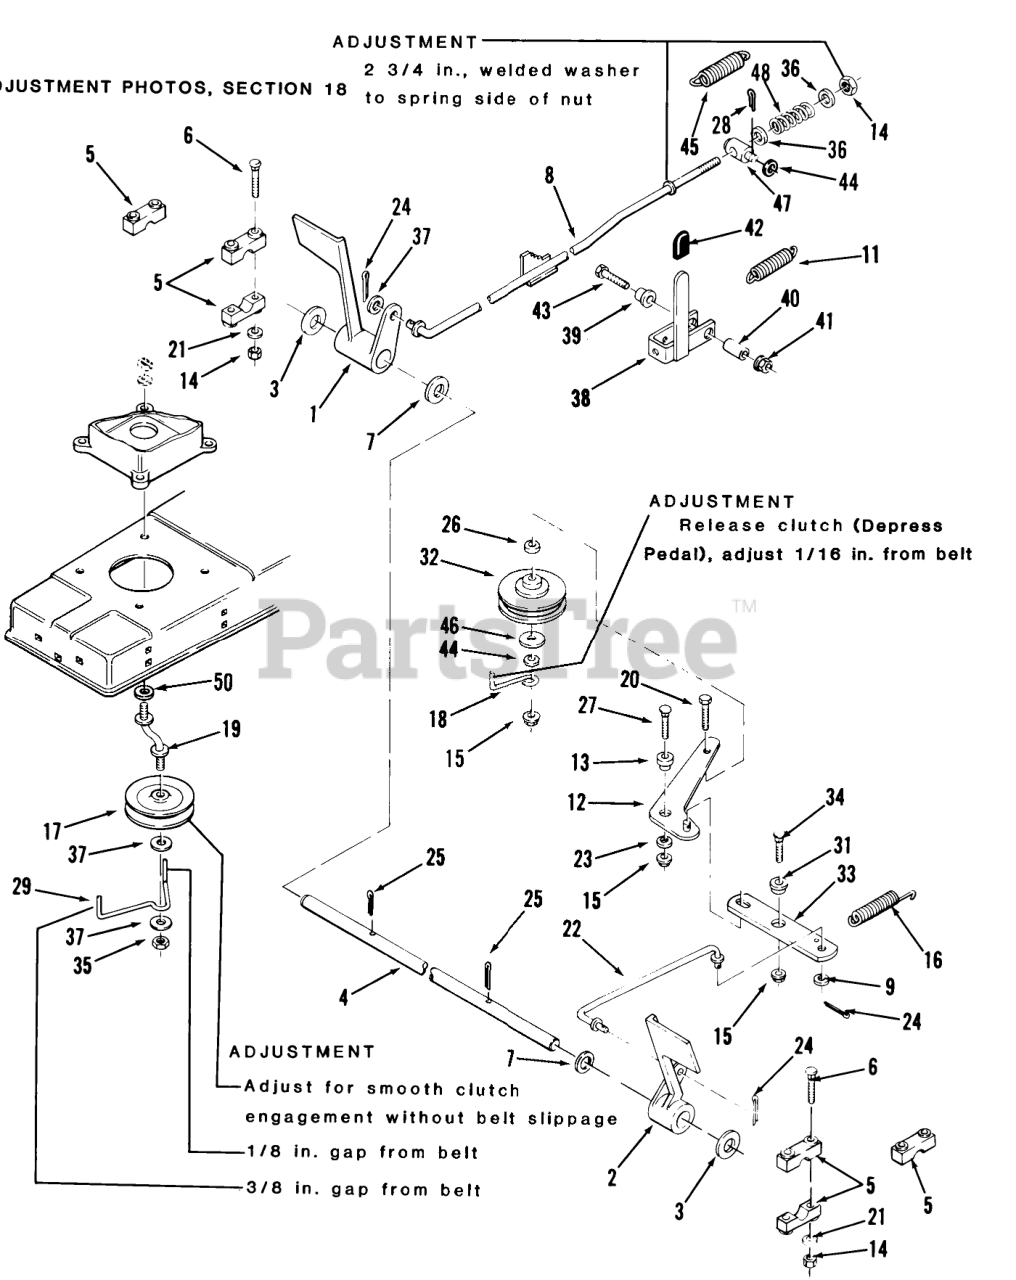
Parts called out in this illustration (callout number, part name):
1	PEDAL-BRAKE R
2	PEDAL CLUTCH R
3	Special Washer
4	SHAFT-PEDAL
5	BLOCK PIVOT
6	Washer
7	Washer
8	Brake Rod 208-3, 211-3 Only
9	WASHER 5/16 SAE
11	SPRING-EXTENSION
12	IDLER ARM ASSY R
13	SPACER-IDLER ARM
14	Nut
15	LOCKNUT-FLANGE
16	SPRING
17	PULLEY-IDLER STATION
18	RETAINER-BELT
20	Bolt
21	WASHER 5/16 SAE
22	ROD-CLUTCH R
23	Washer
24	Pop Rivet
26	SPACER
27	Carriage Bolt
28	Cotter Pin
29	RETAINER-BELT
31	SPACER
32	IDLER PULLEY
33	BAR-CLUTCH
34	Bolt
35	Nut
36	Collar
37	Washer
38	PAWL & HANDLE ASSY
39	SPACER
40	SPACER
41	LOCKNUT-FLANGE
42	GRIP
43	Bolt
44	Washer
45	SPRING-EXTENSION
46	WASHER
47	TRUNNION-LIFT
48	SPRING FRICTION
50	Washer-Lock
